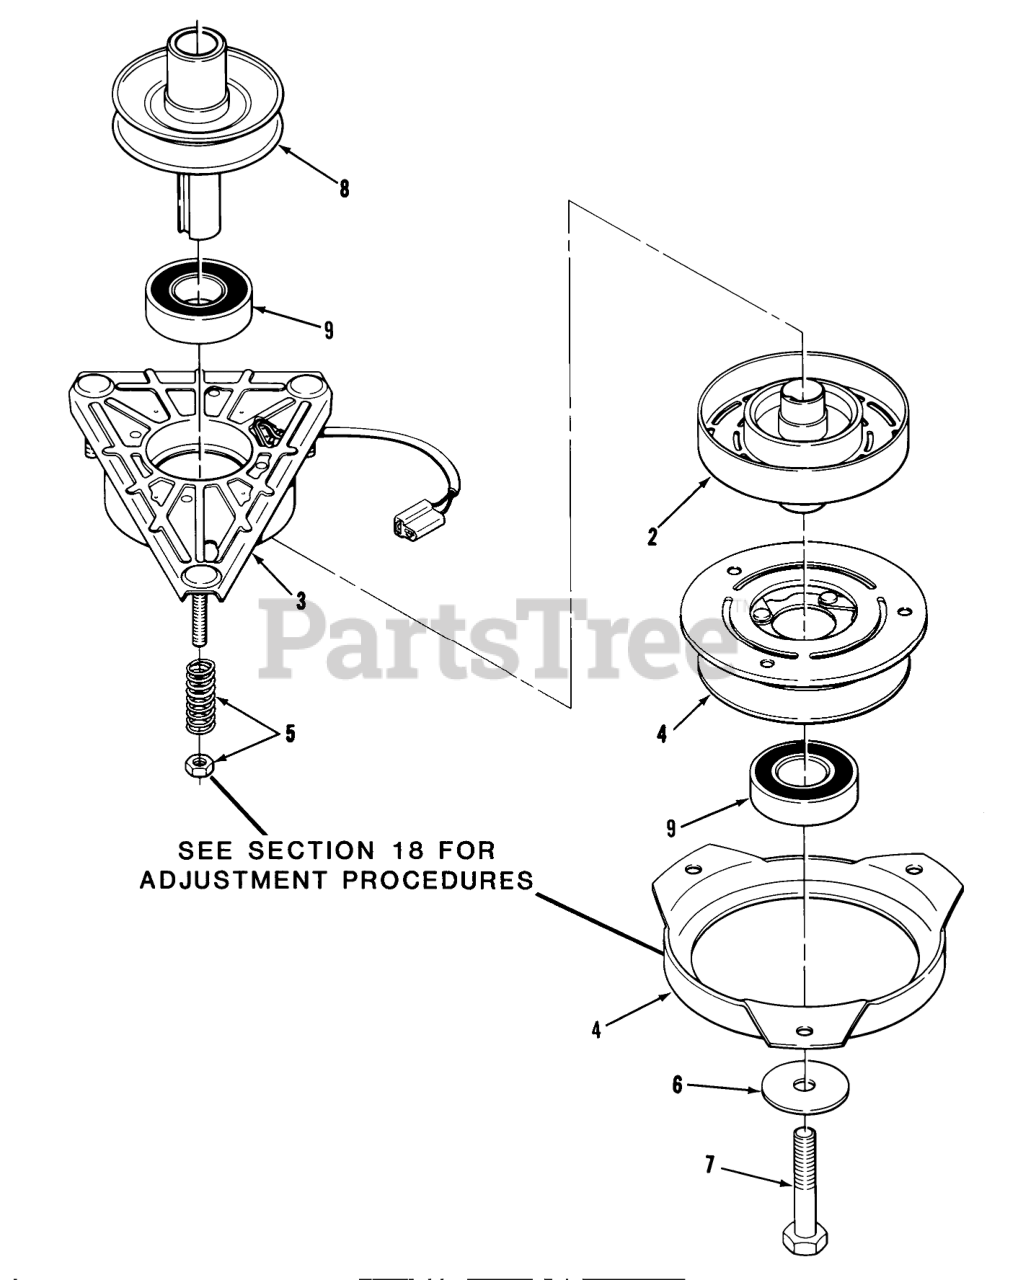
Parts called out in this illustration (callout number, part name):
2	ASS'Y-ROTOR
3	Field Assy (includes one of item 9)
4	Armature and Pulley Assy (includes one of item 9 and Brake Plate)
5	ACCESS SPRING & NUT
6	WASHER
7	Bolt 7/16-20 X 4-1/4 208-5
7	Bolt
7	HHCS M10X1.5X120
8	PULLEY-ENGINE
9	BEARING-ELEC CLUTCH
